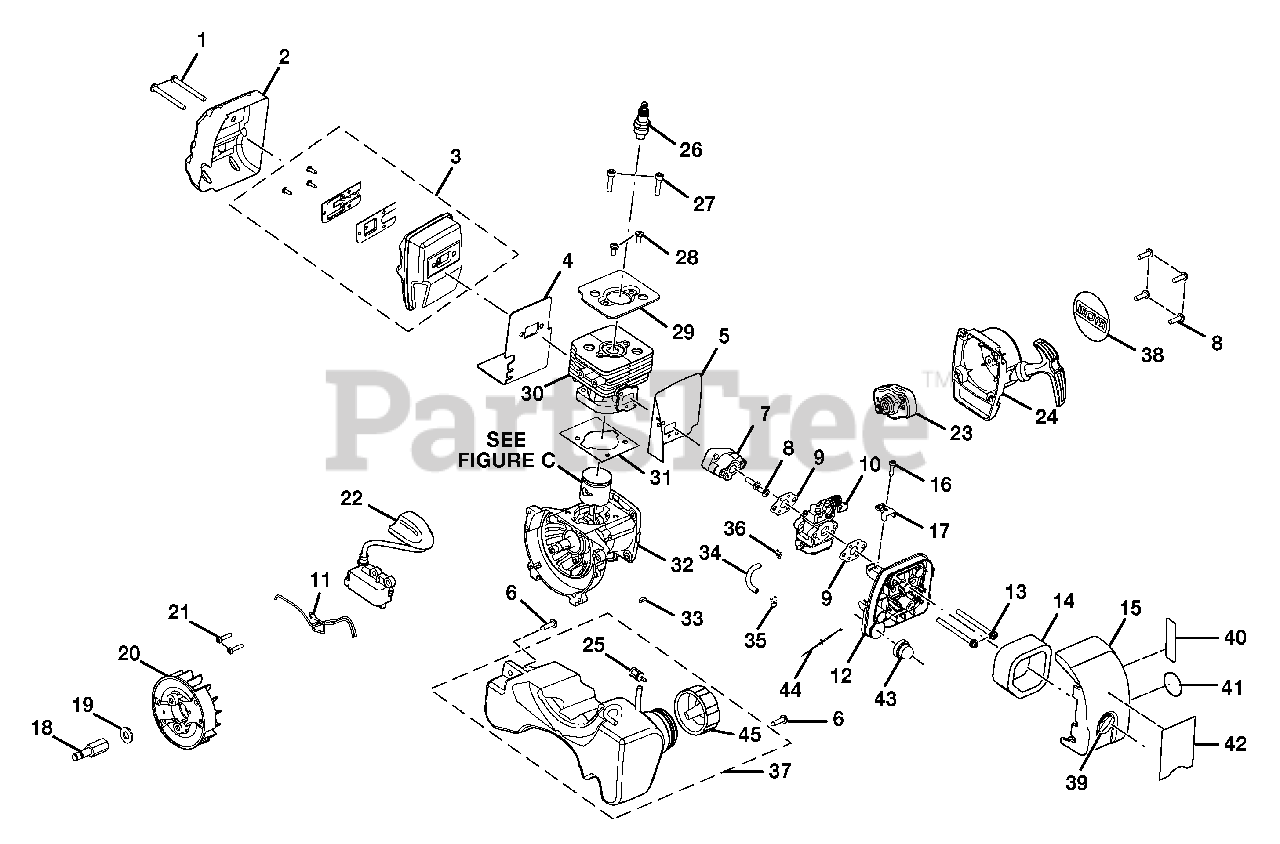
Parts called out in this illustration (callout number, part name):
1	SCREW (M5 X 50 mm)
2	HEAT SHIELD
3	MUFFLER ASSEMBLY
4	GASKET MUFFLER
5	INSULATOR GASKET
6	SCREW (#10-14 X 7/8 in.)
7	INSULATOR
8	SCREW AND WASHER (M5 X 22 mm)
9	CARBURETOR GASKET
10	CARBURETOR
11	LEAD ASSEMBLY
12	AIR BOX BASE
13	SCREW (M5 X 60 mm)
14	AIR FILTER ELEMENT
15	CARBURETOR HOUSING COVER
16	SCREW (M4 X 1.75 X 16 PAN HD.)
17	CLIP-THROTTLE CABLE
18	CRANKSHAFT EXTENSION
20	FLY-WHEEL ASSEMBLY
21	SCREW (M4 X 22 mm)
22	COIL & BOOT ASSEMBLY
23	PULLEY ASSEMBLY
24	STARTER ASSEMBLY
25	FUEL FILTER
26	SPARK PLUG (CHAMPION RCJ4)
27	SCREW (M5 X 22 mm)
28	SCREW & WASHER (M5 X 10 mm)
29	PLATE FOR CYLINDER
30	CYLINDER
31	CYLINDER GASKET
32	CRANKCASE ASSEMBLY
33	KEY WOODRUFF (S43C)
34	TUBING RUBBER
35	CLIP-HOSE (ID 4.9)
36	CLIP-HOSE
37	FUEL TANK AND CAP
38	STARTING HOUSING LABEL
39	AIR FILTER KNOB
40	STARTING LABEL
41	ZIP START LABEL
42	STARTING INSTRUCTION LABEL
43	PRIMER ASSEMBLY
44	CABLE ASSEMBLY
45	FUEL CAP ASSEMBLY
